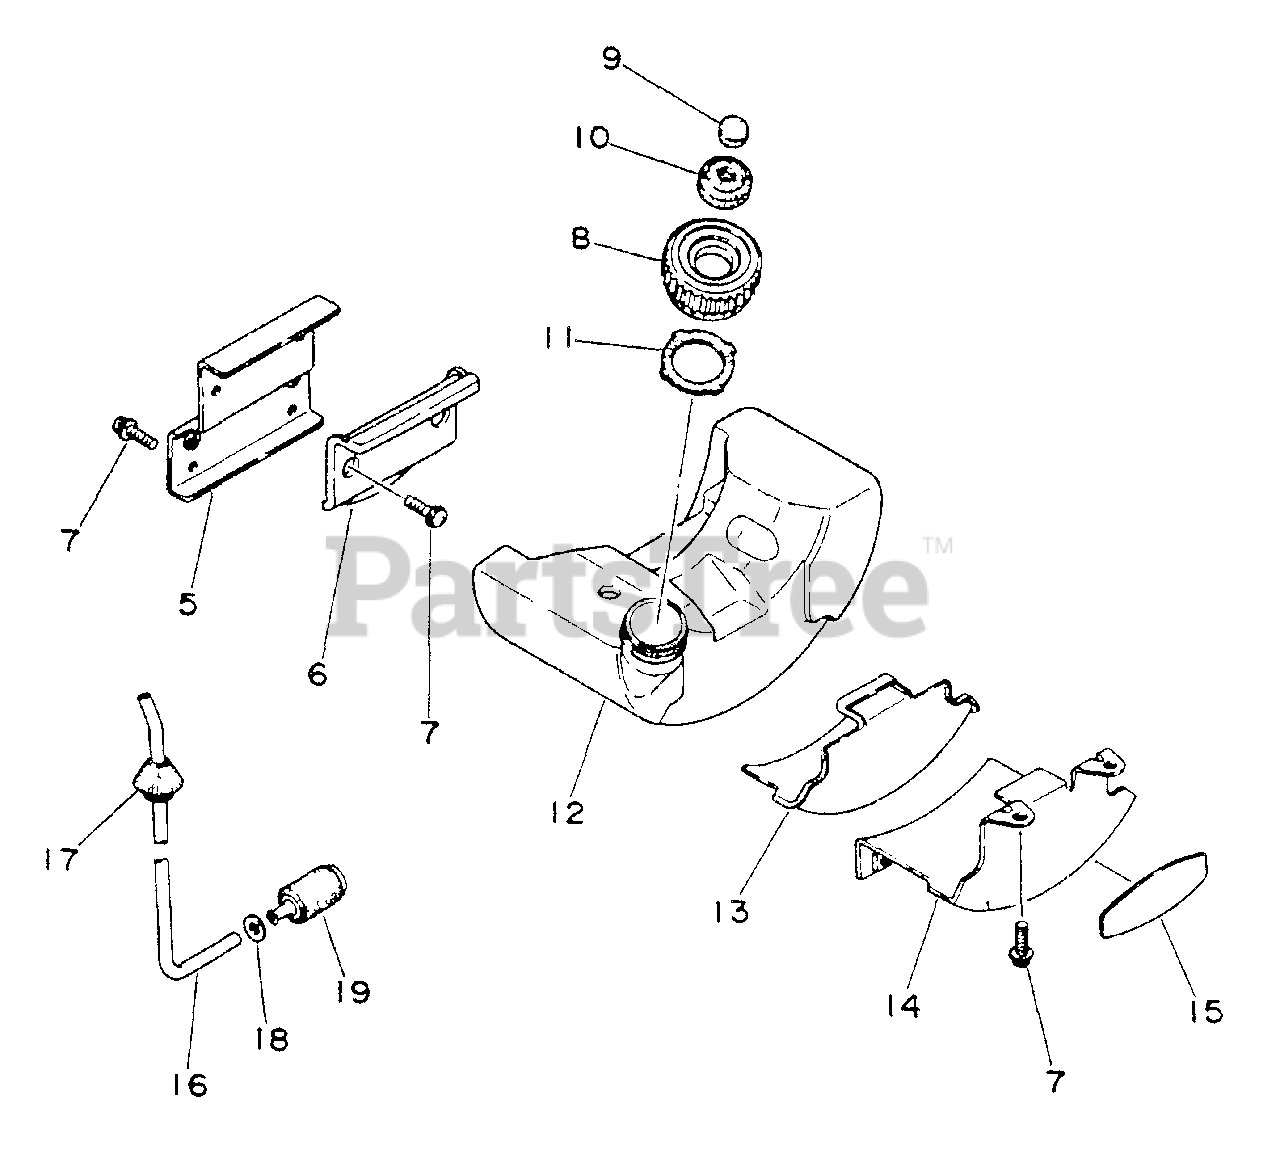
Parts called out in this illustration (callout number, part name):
5	BRACKET, FUEL TANK
6	CUSHION, FUEL TANK
7	SCREW 4×14
8	CAP ASSY
9	FILTER, CHECK VALVE
10	VENT ASSY
12	TANK, FUEL
14	BRACKET, FUEL TANK
15	LABEL - ECHO
18	WASHER 5.5×12×0.8
19	FILTER, FUEL
